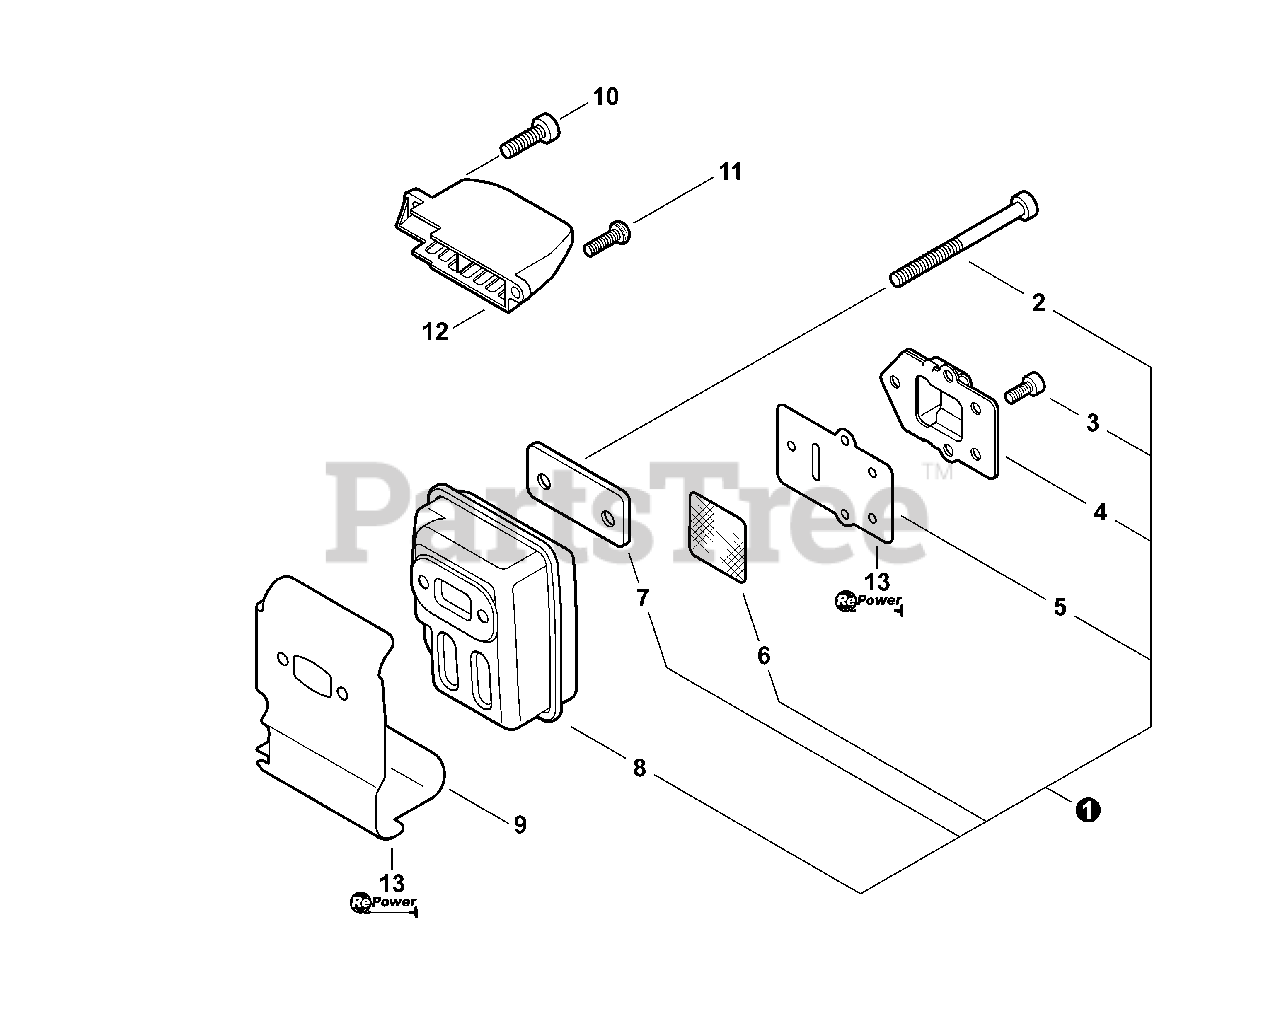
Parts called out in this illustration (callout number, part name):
1	MUFFLER ASSY
2	BOLT, TORX 5×55
3	BOLT, TORX 4×8
4	GUIDE, EXHAUST
5	GASKET, EXHAUST
6	SCREEN, SPARK ARRESTER
7	PLATE, EYE
8	MUFFLER
9	HEAT SHIELD, EXHAUST
10	BOLT, TORX 5×16
11	BOLT, TORX 5×16
12	COVER, MUFFLER
13	GASKET KIT
